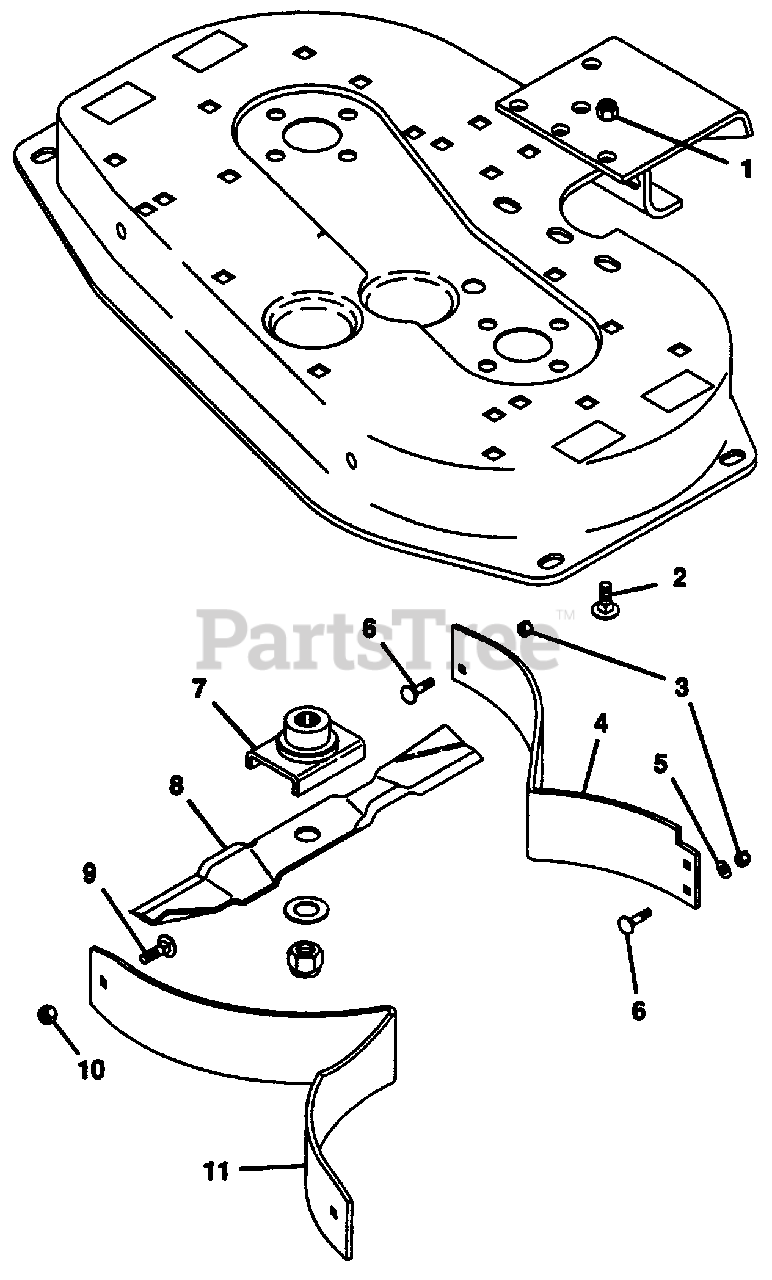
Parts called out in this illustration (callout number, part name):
1	Nut, Lock 3/8-16
2	Bolt, Carriage 3/8-16x.75
3	Nut, Lock 1/4-20
4	Baffle, Mulching
5	Washer, Flat .281x.625x.065
6	Bolt, 1/4-20x.625 Rd Hd Sq Nk
7	Weldment, Blade Cradle
8	Blade, Mulching 40" Mower
9	Bolt, 5/16-18x.625 Rd Hd Sq Nk
10	Nut, Lock 5/16-18
11	Baffle, Front Mulching
